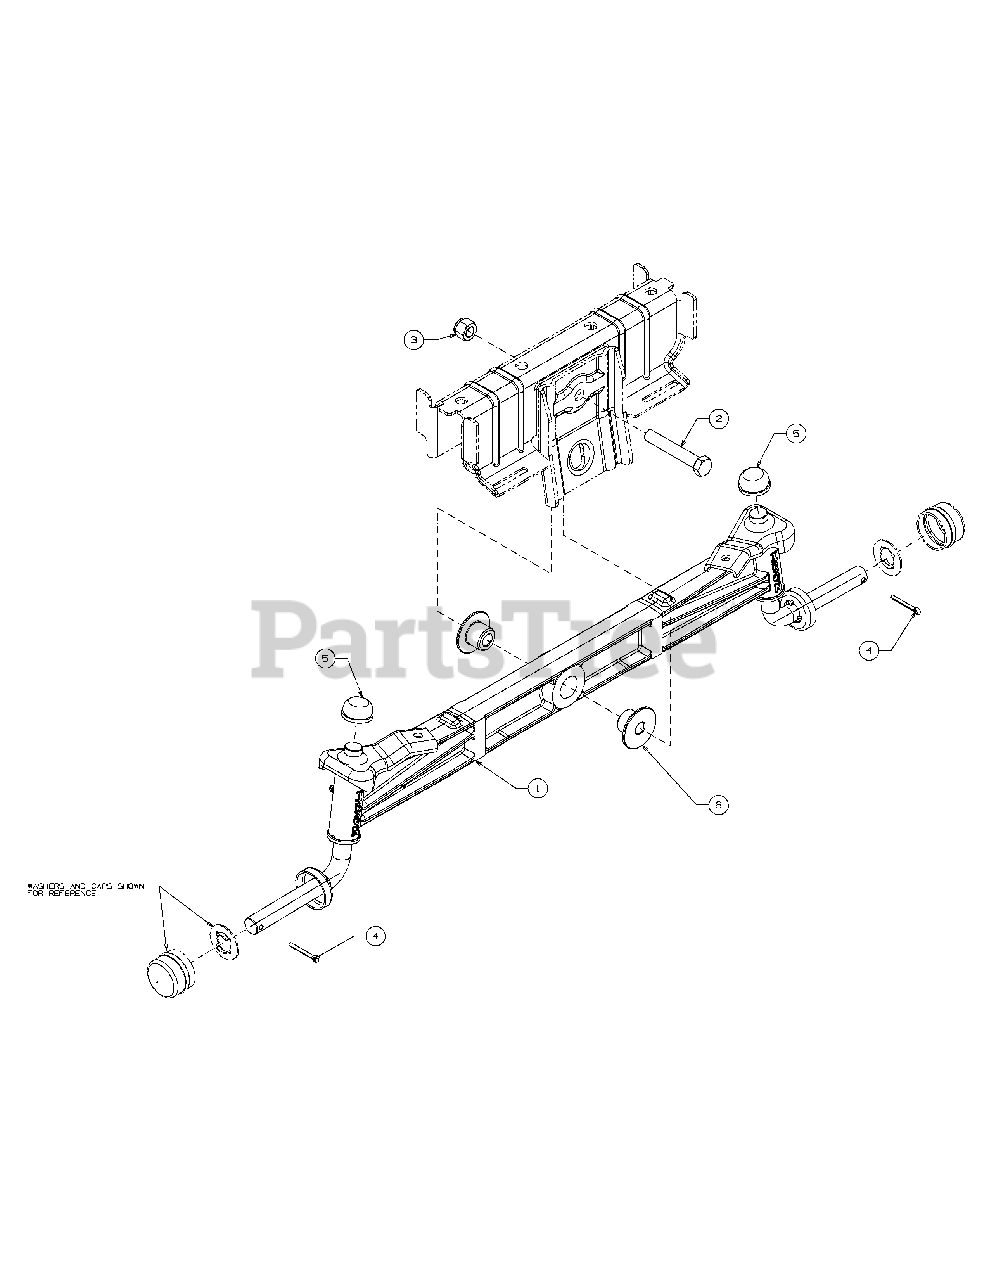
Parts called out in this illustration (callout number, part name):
1	Front Pivot Axle Assembly
2	Screw-Hex 1/2-13 X
3	Nut-Hex Lock Nylon
4	Pin-Cotter-5/32 Di
6	Spacer-Shldr Axle
